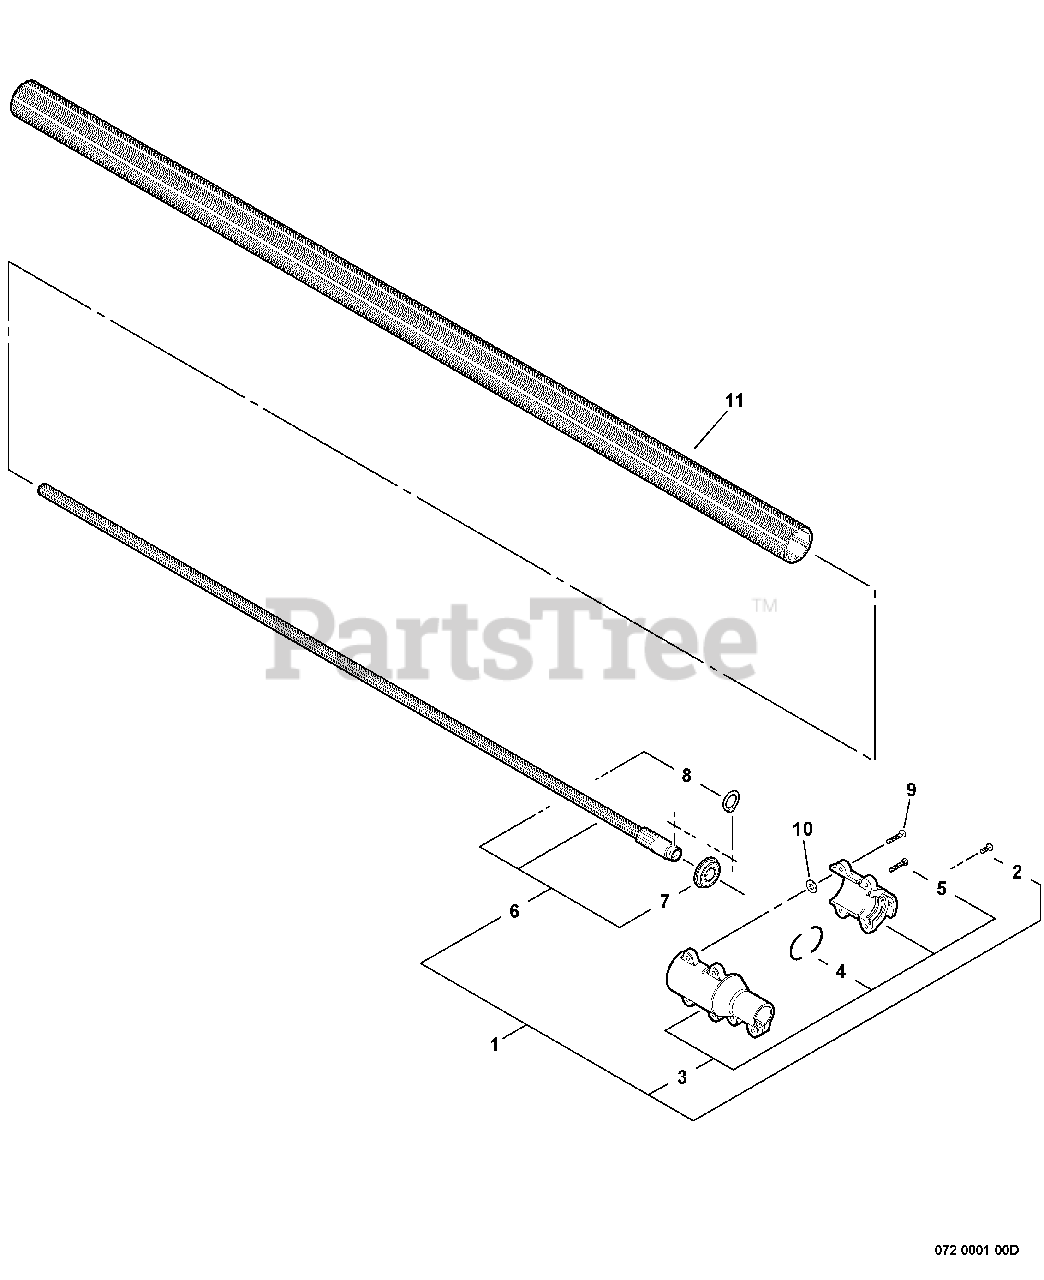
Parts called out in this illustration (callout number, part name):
1	DRIVESHAFT ASSY
2	SCREW - 5X14
3	COUPLING ASSY
4	CUSHION
5	SCREW - 5X20
6	DRIVESHAFT ASSY - LOWER
7	BEARING, BALL - 6002
8	RING, RETAINING
9	SCREW - 5X20
10	WASHER - 5
11	PIPE, MAIN - ORANGE
